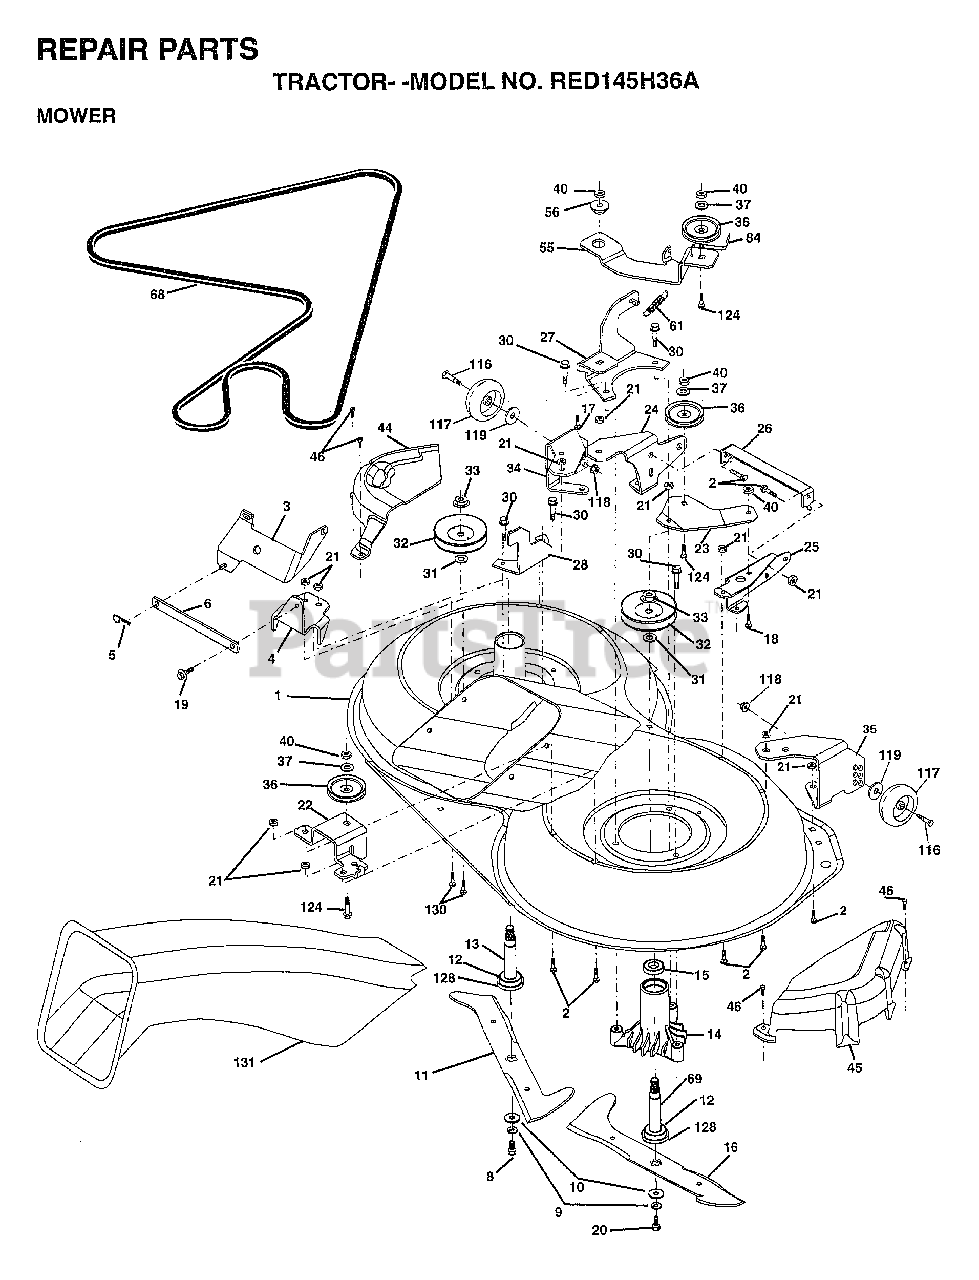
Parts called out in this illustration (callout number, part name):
1	HOUSING.ASM.MOWER
2	BOLT
3	BRKT.ASM.S-BAR.CHASSIS
4	BRKT.BAR.SWAY.DECK
6	BAR.SWAY.92.CRD
8	BLADE BOLT
10	WASHER.HARD.BLADE
11	BLADE.3-1.LH.92.CRD
12	BEARING.BALL
14	HSG ASM MANDREL
15	BEARING
16	BLADE.3-1.RH.CRD.92
17	BOLT.3/8-14X1.25
18	BOLT D
19	BOLT SHD 5/16-18
20	BOLT.3/8-24X1.25
22	BRKT.IDLER.SPRT.CRD
23	"BRKT.IDLER.SPRT.RF.92,CRD"
24	BRKT.SUSP.LF.92.CRD
25	BRKT.SUSP.RF.92.CRD
26	BRACE.SUPT.SUSP.FRT.CRD
27	BRKT.ASM.SUSP.RR.92.CRD
28	BRKT.ASM.SUSP.LR.92.CRD
30	"SCREW-THD ROLL,WA"
31	WASHER
32	PULLEY.MAND.36/46
34	BRKT.GUAGE.WHL.LF.92.CRD
35	BRKT.GUAGE.WHL.RF.92.CRD
36	PULLEY.IDLER.4.25
37	WASHER
44	COVER.MANDREL.LH.92.CRD
45	COVER.MANDREL.RH.92.CRD
46	SCREW.1/4-20X5/8
55	ARM.IDLER.92.CRD
56	SPACER RETAINER
61	SPRING.TENSION.BELT
68	HEX-BELT.92.MWR.105AA
69	SHAFT.ASM.W/LWR.BRG.RH.THD
84	"KEEPER-BELT,IDLER"
116	BOLT.SHOULDER
117	WHEEL GAGE DONUT
118	LOCKNUT
119	WASHER
124	BOLT.3/8-16X1.50
128	WASHER.FELT.
131	CHUTE.BAGGER.CRD
